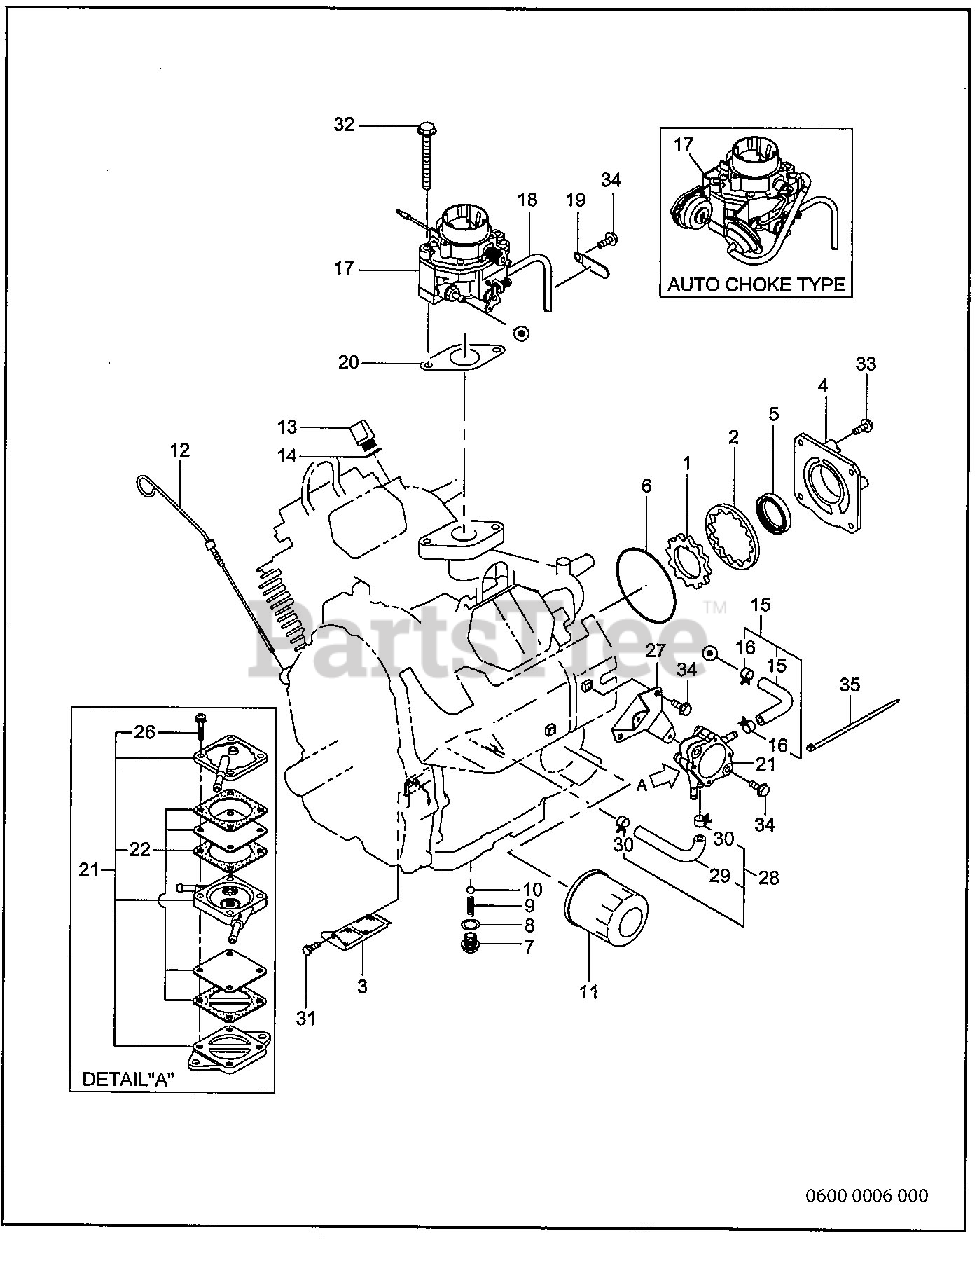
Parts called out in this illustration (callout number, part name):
3	OIL PUMP FILTER UNIT
4	OIL PUMP COVER ASSY
7	PLUG, oil relief
8	GASKET, aluminum
9	SPRING, relief valve
11	OIL FILTER ASSY
12	OIL GAUGE ASSY
13	OIL FILTER CAP
15	FUEL PIPE ASSY
15	RUBBER PIPE (1/4" x 1/2" )
17	CARBURETOR ASSY
20	GASKET, carburetor
21	FUEL PUMP ASSY
22	DIAPHRAGM GASKET SET
27	BRACKET, fuel pump
28	PULSE PIPE ASSY
29	RUBBER PIPE (1/4" x 1/2" )
31	BOLT
32	FLANGE BOLT
33	FLANGE BOLT
34	FLANGE BOLT
